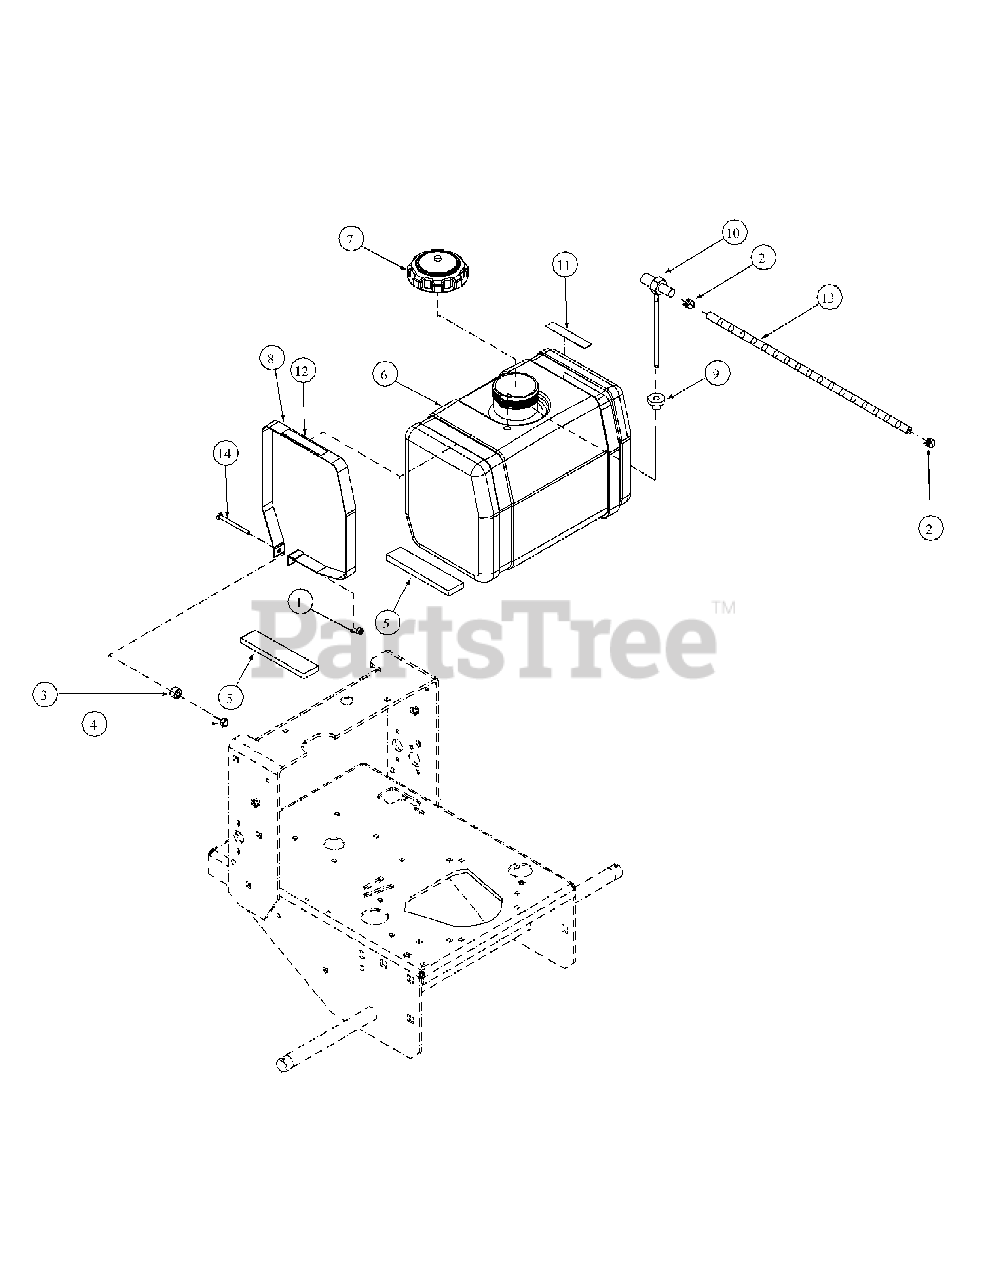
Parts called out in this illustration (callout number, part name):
1	Lock Nut, Nylon Insert, 1/4-20
2	Uni-Clamp
3	Spacer
4	Nut, 1/4-20
5	Rubber Stop Pad
6	Fuel Tank
7	Fuel Cap, 3.5
8	Fuel Tank Strap
9	Grommet Fuel Tank
10	Shut Off Fuel Tank
11	Label, Mower Warning Turn Off Engine
12	Label, Mower Instruction, Fuel Valve
13	Hose Fuel, 22" x .25 ID
14	Carriage Bolt, 1/4-20 x 3.00
